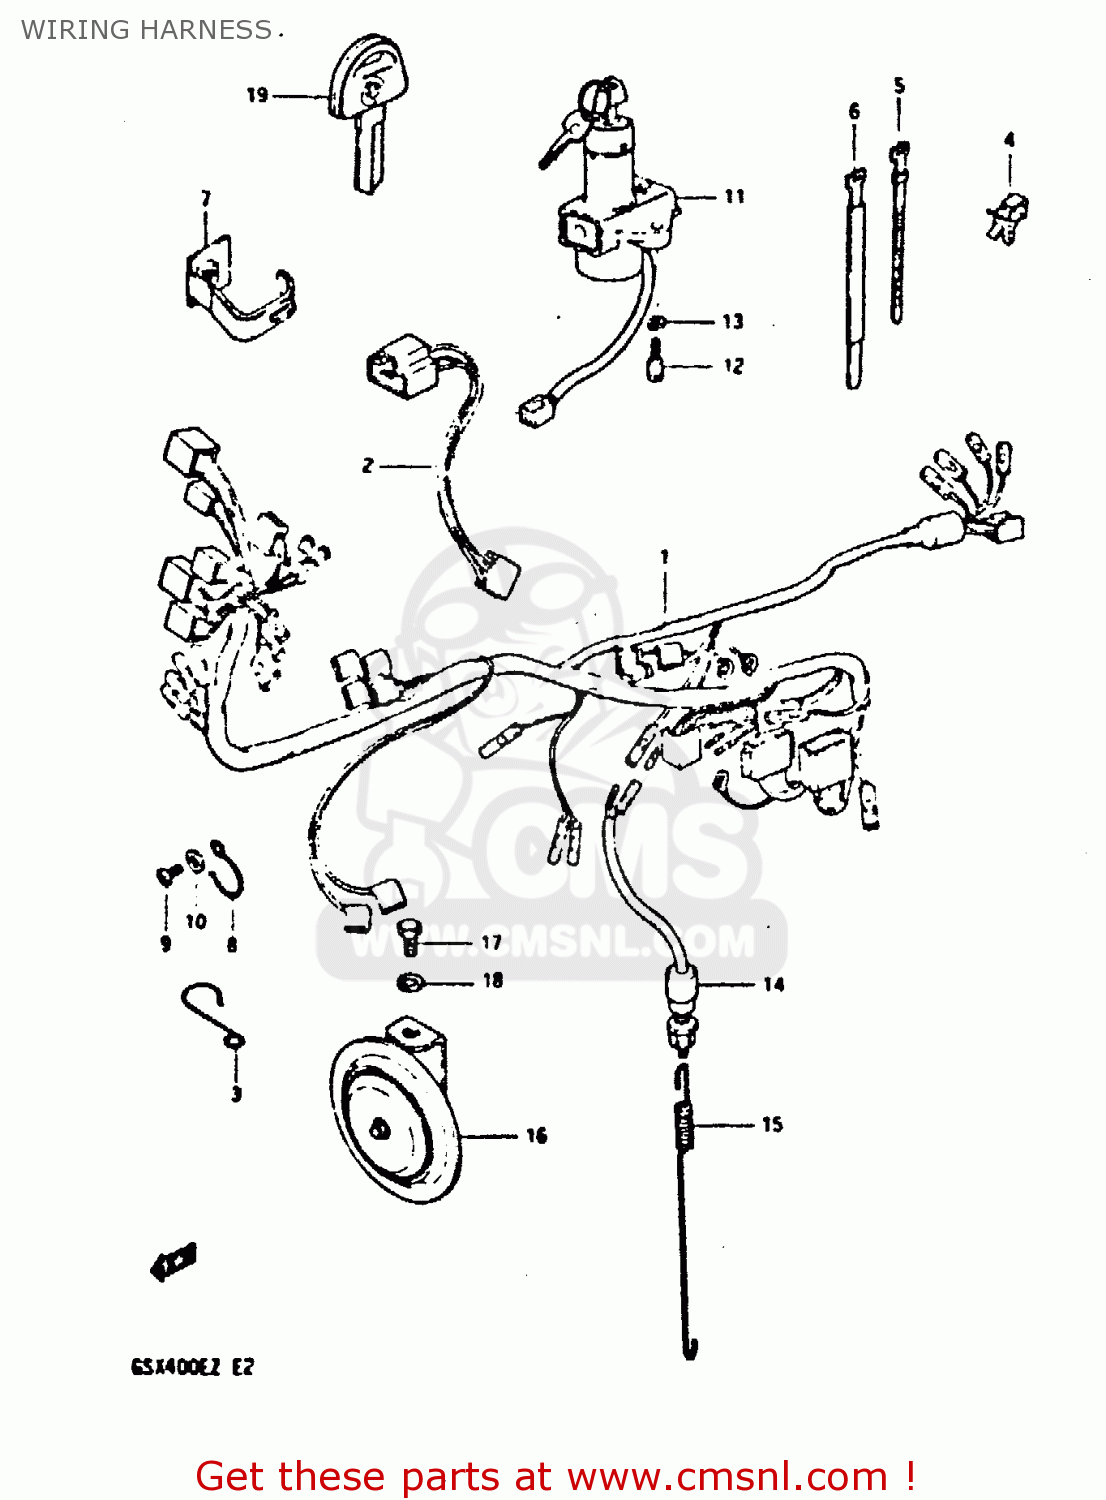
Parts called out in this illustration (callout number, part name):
1	WIRING HARNESS
2	LEAD WIRE,HEADLAMP
3	CLIP,WIRING HARNESS
4	CLIP
5	CLAMP(L:120)
6	CLAMP
7	CLAMP,WIRING HARNESS
8	GUIDE,WIRING HARNESS
9	SCREW 6X12
10	WASHER 6MM
11	SWITCH ASSY,IGNITION
12	BOLT
13	LOCK WASHER
14	SWITCH ASSEMBLY,STOP LAMP
15	SPRING
16	HORN ASSEMBLY
17	BOLT 8X12
18	WASHER
19	KEY,BLANK
